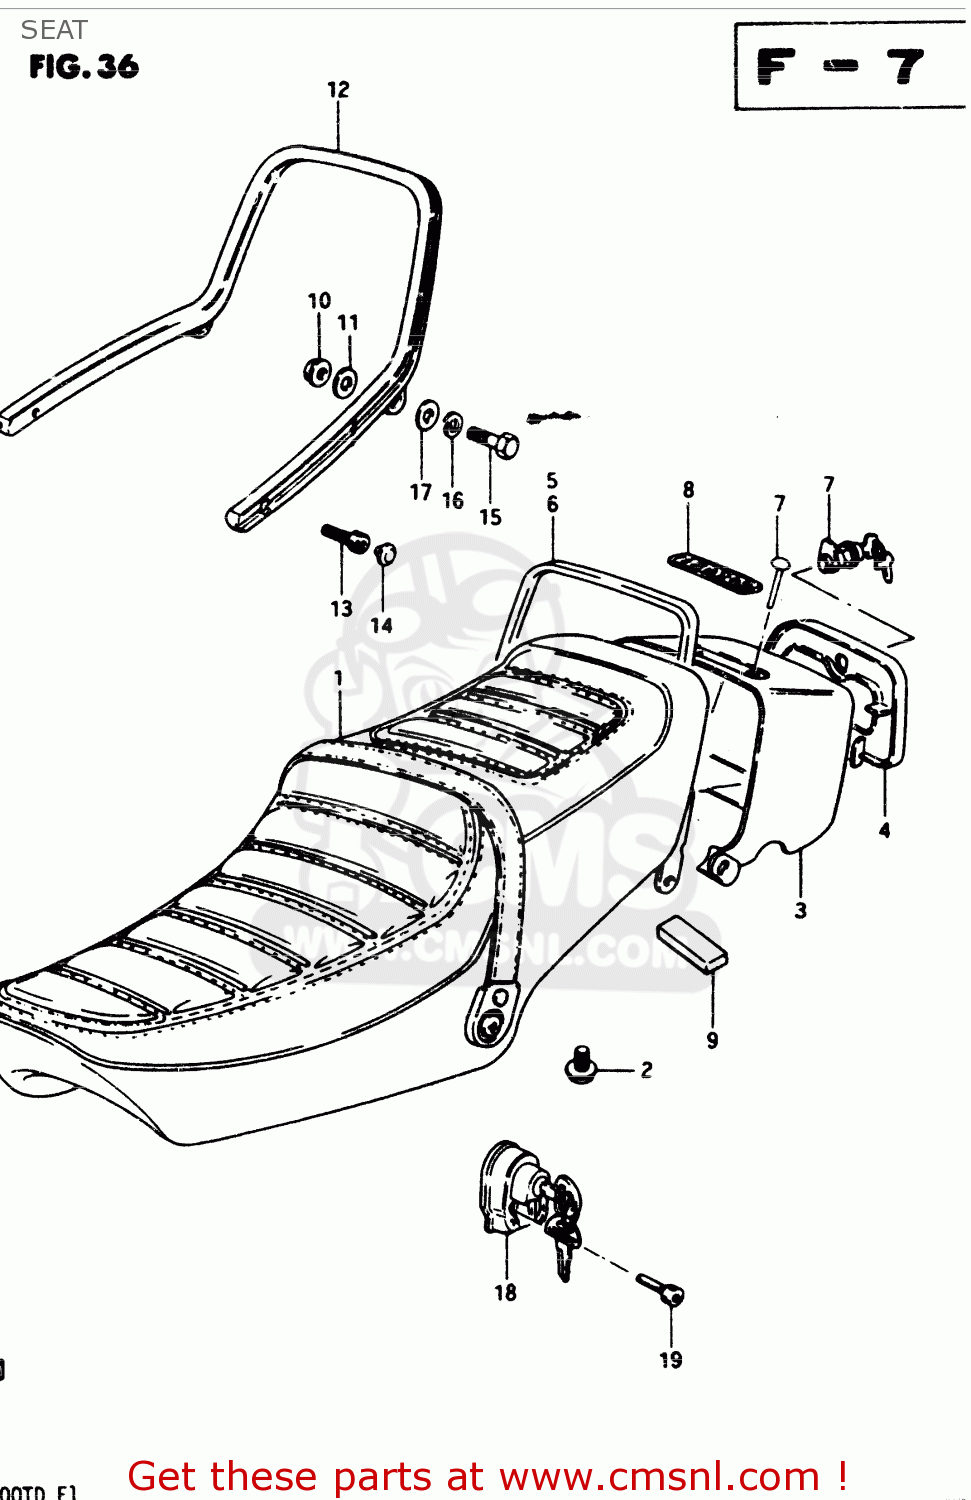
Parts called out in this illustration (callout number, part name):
1	SEAT ASSY (BLACK)
2	BOLT
3	COVER,SEAT TAIL
4	LID,TAIL COVER
5	WEATHERSTRIP,TAIL COVER
6	WEATHER STRIP, TAIL COVER NO.2
7	RIVET
8	EMBLEM
9	CUSHION,TAIL SEAT COVER
10	WASHER (6.7X16X1.8)
11	NUT
12	LOCK SET,TAIL COVER
13	HANDLE, PILLION RIDER
14	BOLT
15	CAP(OD:14.5)
16	BOLT
17	LOCK WASHER
18	WASHER
19	LOCK ASSY,HELMET
20	BOLT 5X25
